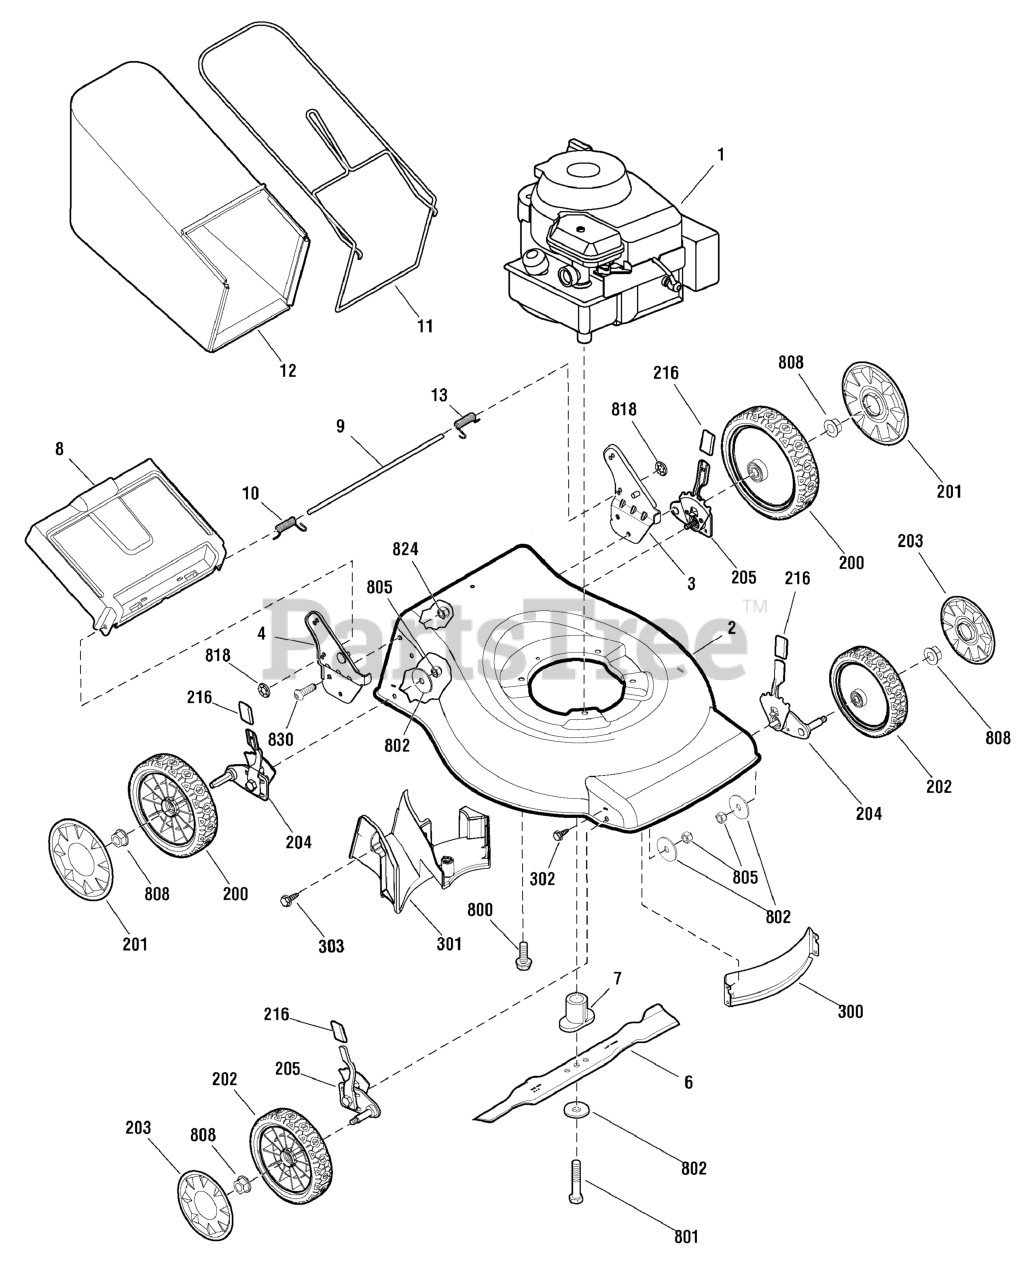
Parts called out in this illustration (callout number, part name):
1	* ENGINE, 5.5GT Briggs & Stratton
2	MOWER HOUSING
3	BRACKET ASSEMBLY, Left Handle
4	BRACKET ASSEMBLY, Right Handle
6	BLADE, 16 in
7	BLADE ADAPTER ASSEMBLY
8	DOOR, Rear
9	ROD, Rear Door
10	SPRING, Torsion Rear Door, Right
11	FRAME ASSEMBLY
12	BAG ASSEMBLY
13	SPRING, Torsion Rear Door, Left
200	WHEEL, Rear
201	HUBCAP, Rear
202	WHEEL, Front
203	HUBCAP, Front
204	HEIGHT ADJUSTER ASSEMBLY, Left
205	HEIGHT ADJUSTER ASSEMBLY, Right
216	GRIP, Height Adjustment
300	BAFFLE, Front, 16
301	BAFFLE, Rear, 16
302	SCREW, Pan Head, Taptite, 1/4-20 x 1/2
303	SCREW, Pan Head, Taptite, 1/4-15 x 5/8
800	CAPSCREW, Hex Head, 3/8-16 x 1
801	BOLT, Blade, 3/8-24 x 2
802	WASHER, Belleville
805	NUT, Nylock, M8 x 1-1/4
808	NUT, Flange, 3/8-16
818	PUSHNUT, 1/4
824	NUT, Flange, 5/16-18
830	CAPSCREW, 5/16-18 x 3/4
1000	DECAL KIT
